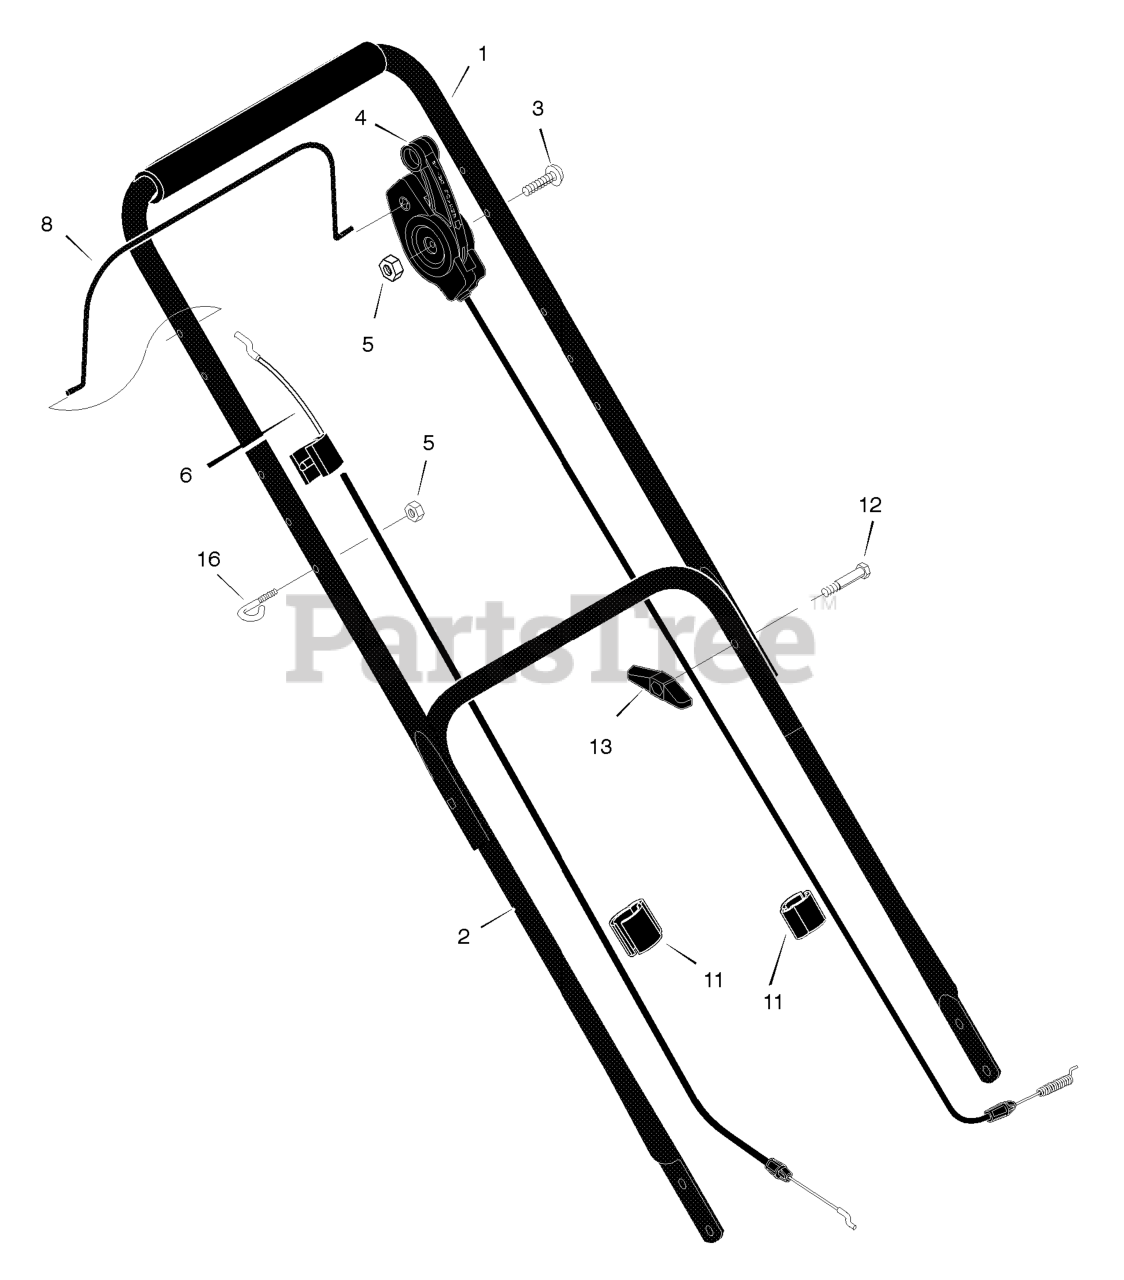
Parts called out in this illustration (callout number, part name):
1	Handle, Upper (Gray)
2	Handle, Lower (Gray)
4	Control, Drive
5	Locknut
6	Cable, Stop
8	Lever, Stop
11	Fastener, Cable
13	Knob
16	Guide, Rope
